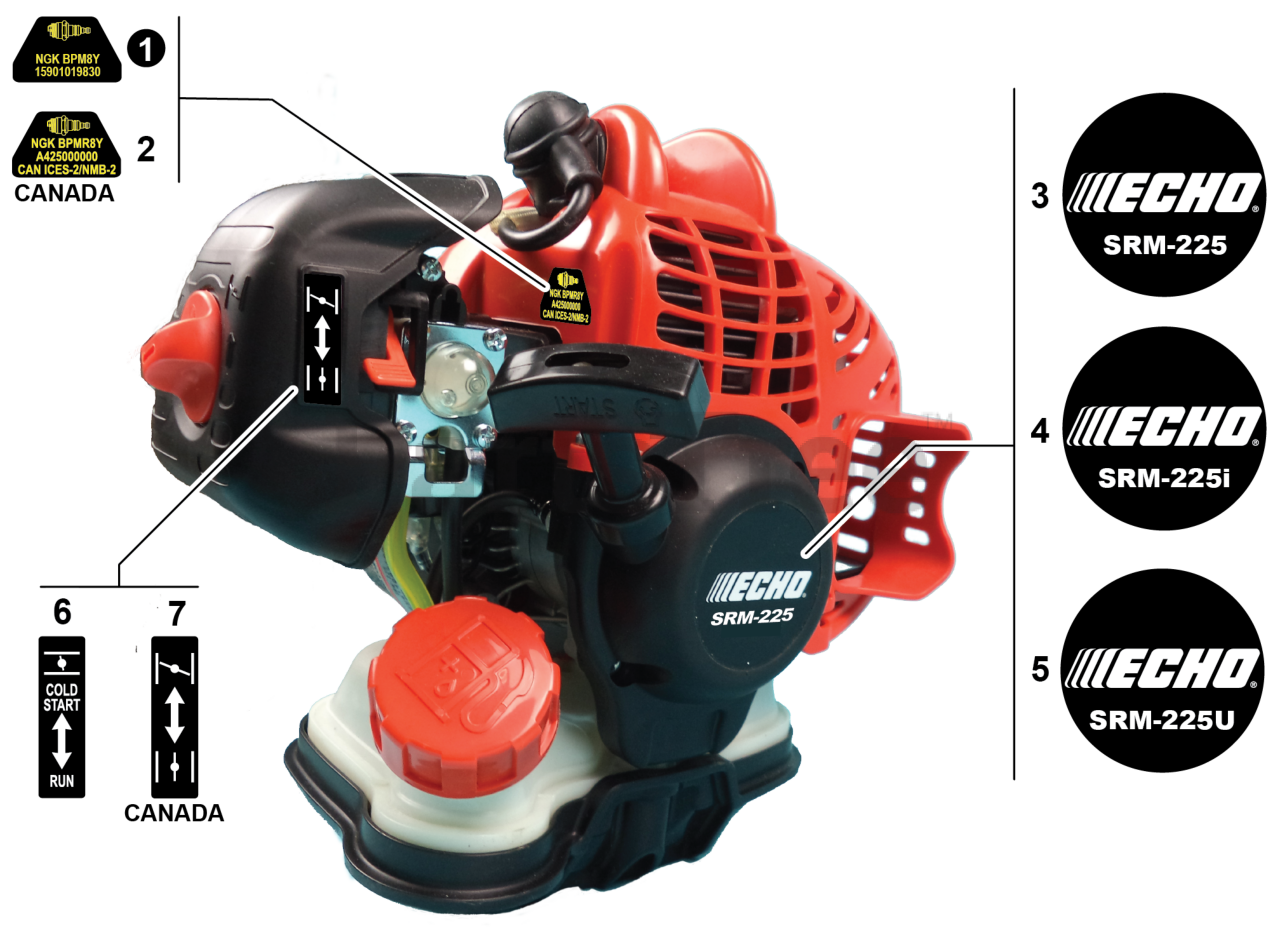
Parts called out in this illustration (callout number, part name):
1	LABEL - SPARK PLUG - BPM8Y
2	LABEL - SPARK PLUG - BPMR8Y
3	LABEL - STARTER - SRM-225
4	LABEL - STARTER - SRM-225I
5	LABEL - STARTER - SRM-225U
6	LABEL - CHOKE
7	LABEL - CHOKE
